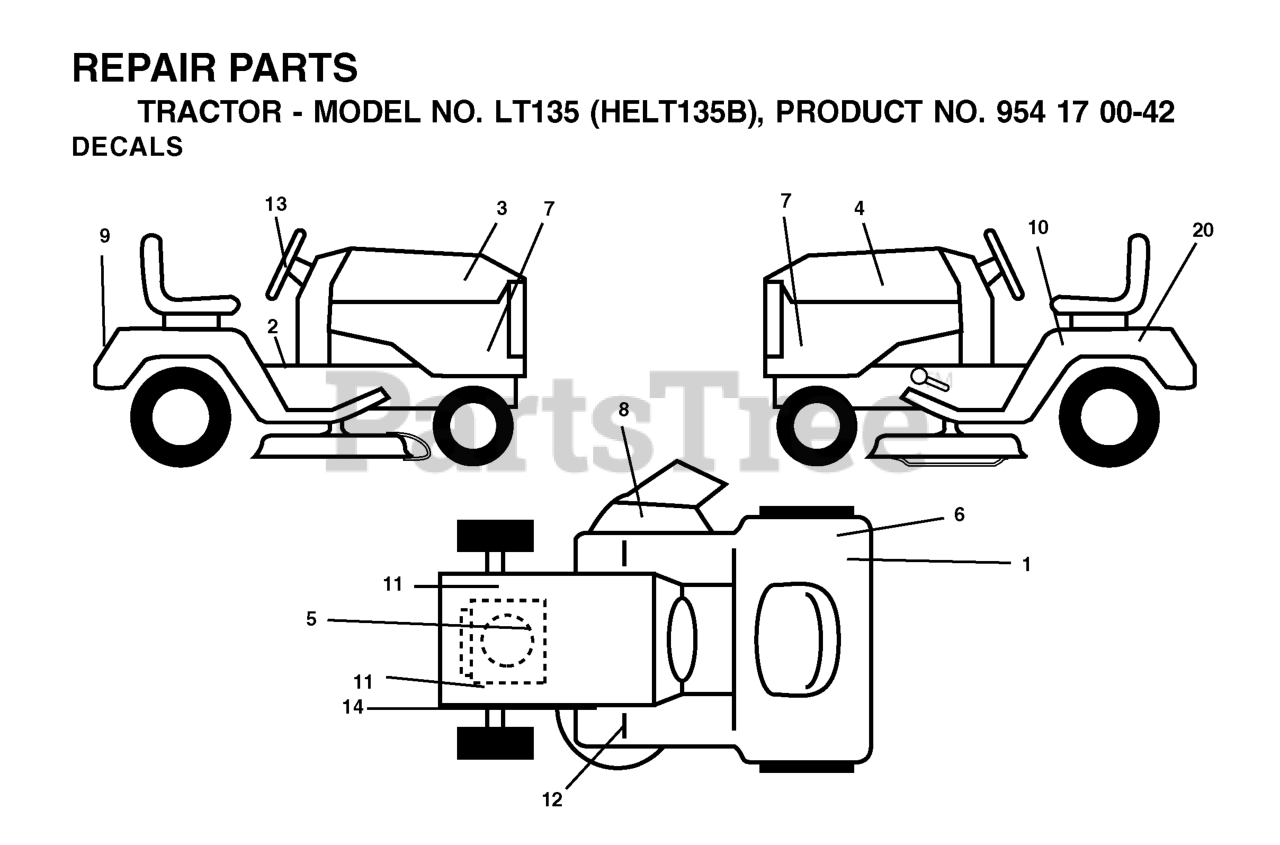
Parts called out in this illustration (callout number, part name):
1	DECAL CERTIFICATION
2	DECAL PARK BRAKE
6	DECAL EUROPE STANDARD CE
7	DECAL PNL SIDE
8	DECAL MOWER CUT/FINGER
9	DECAL FENDER HUSQ
10	DECAL READ OWNER'S MAN SYMS
12	DECAL
13	DECAL.WHEEL.STEERING.HUSQ.PERM
14	DECAL V-BELT SCHEMATIC
20	DECAL BTRY SYMBOLS
